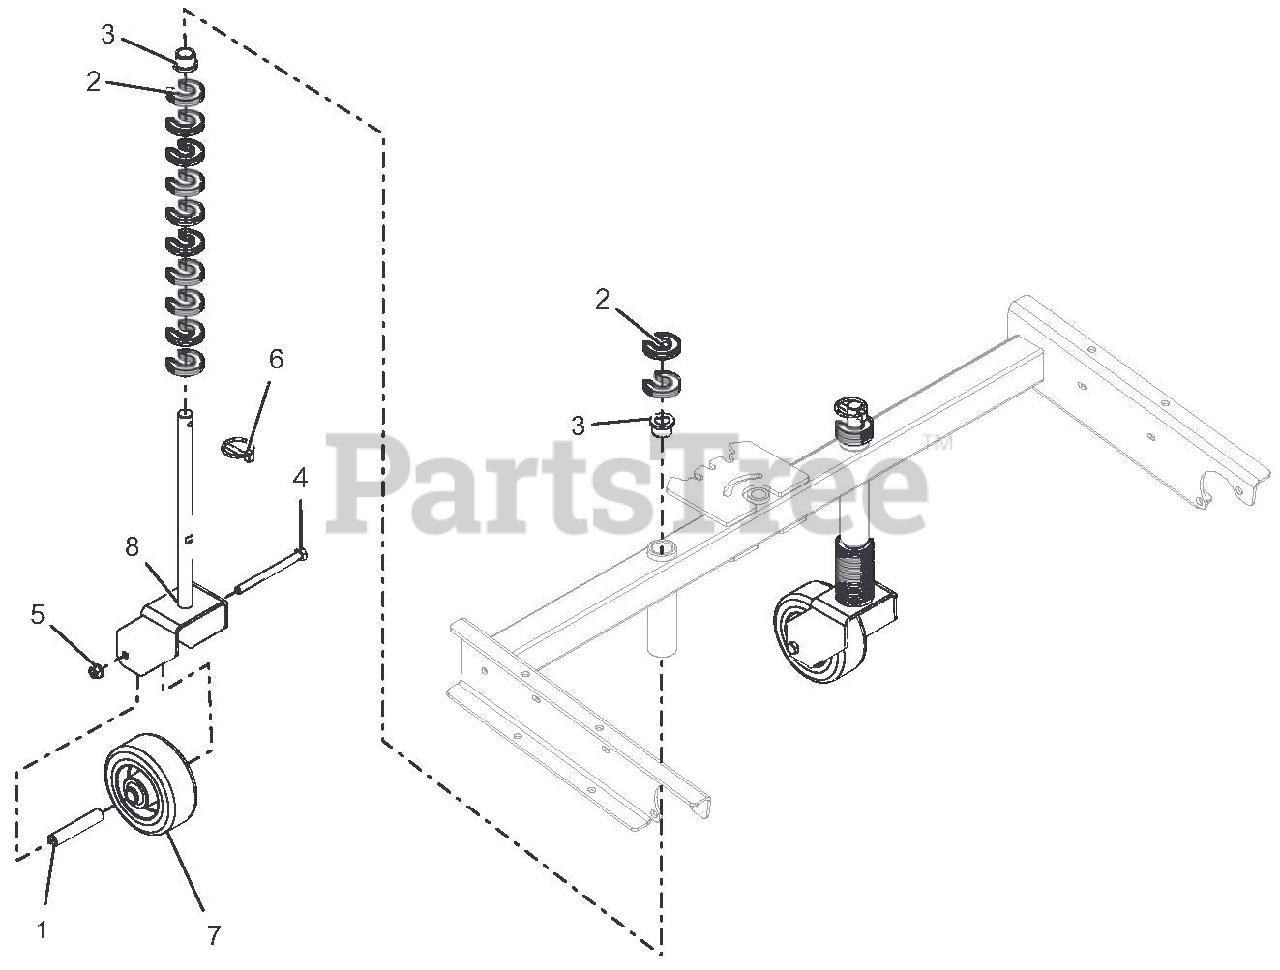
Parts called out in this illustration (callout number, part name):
1	SPCR, CASTER WHEEL
2	CLIP, HOC FIXED
3	BUSHING, FLANGE
4	BLT-HEX .38-16X4.50 GR5 YWZC
5	NUT, LK-TOP-FLG .38-16 YWZC
6	PIN, 1/4 X 1 - 9/16 LYNCH
7	WHEEL, CASTER - 5" OD
8	FORK, CASTER (BLACK)
